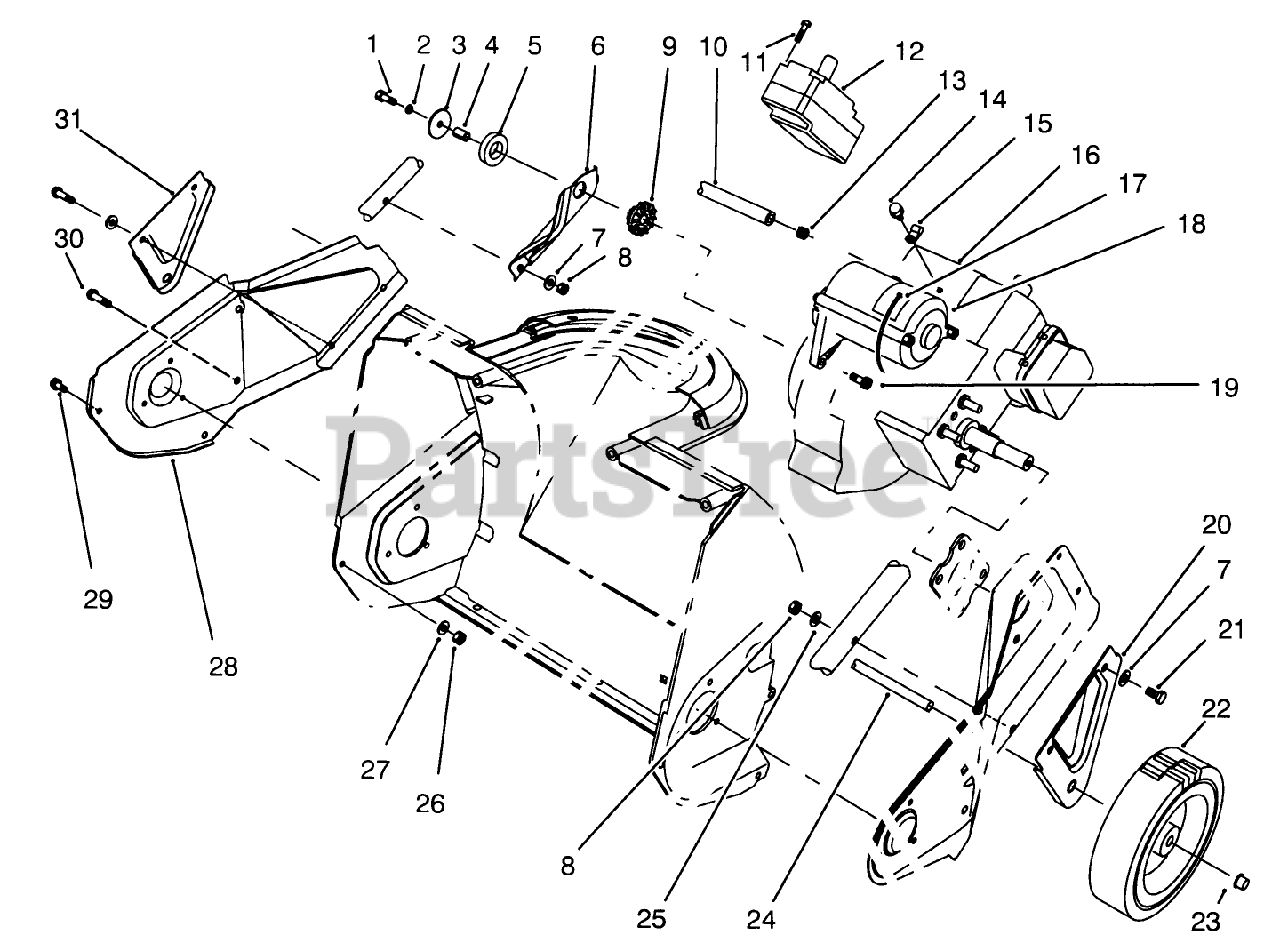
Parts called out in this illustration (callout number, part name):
1	SCREW-HH
2	WASHER-LOCK
4	SPACER-TUBULAR
7	WASHER-FLAT
8	NUT-LOCK, NI
9	BUSHING-ISOLATOR
10	LINE-GAS
11	SCREW-PLASTITE
12	HOUSING-MOTOR AND SWITCH
14	SCREW-HWH
15	CLAMP
17	TIE-CABLE
19	SCREW-HH, TORX
21	SCREW-HH
22	WHEEL
23	NUT-PUSH
24	AXLE SHAFT
25	WASHER
26	NUT-LOCK, NI
27	WASHER-FLAT
30	SCREW-PLASTIC
